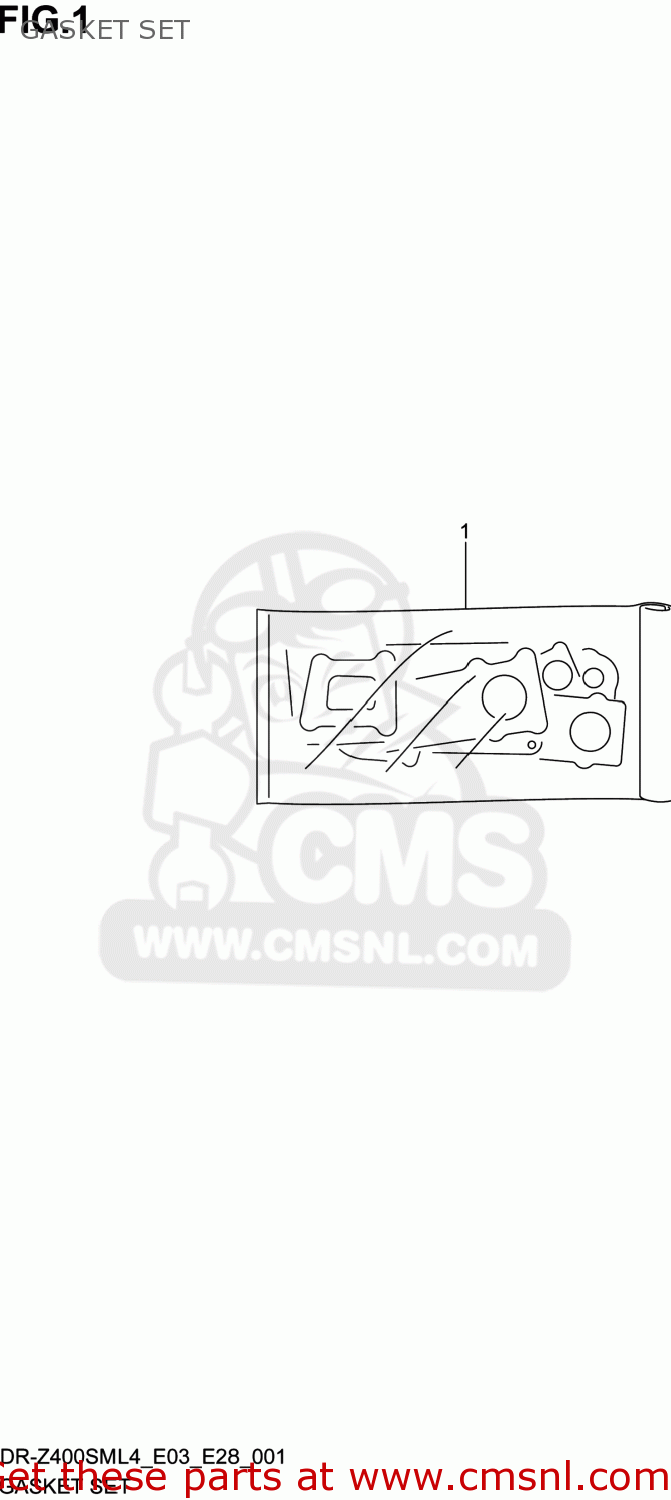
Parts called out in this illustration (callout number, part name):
1	GASKET SET (NAS)
2	GASKET,CYLINDER HEAD (NAS)
3	GASKET,CYL HEAD COVER (NAS)
4	GASKET,CYLINDER (NAS)
5	GASKET,CLUTCH COVER (NAS)
6	GASKET,MAGNETO COVER (NAS)
7	O RING,CLUTCH COVER OUTER
8	GASKET,TENSIONER ADJUSTER (NAS)
9	GASKET,EXHAUST PIPE
10	WASHER,CYL HEAD COVER
11	O RING(D:2.4,ID:11)
12	O RING(D:1.9,ID:13)
13	O RING(D:3.1,ID:16.8)
14	O RING(D:3.1,ID:32.7)
15	O RING(D:2.4,ID:52.6)
16	O RING(D:2.6,ID:67.1)
